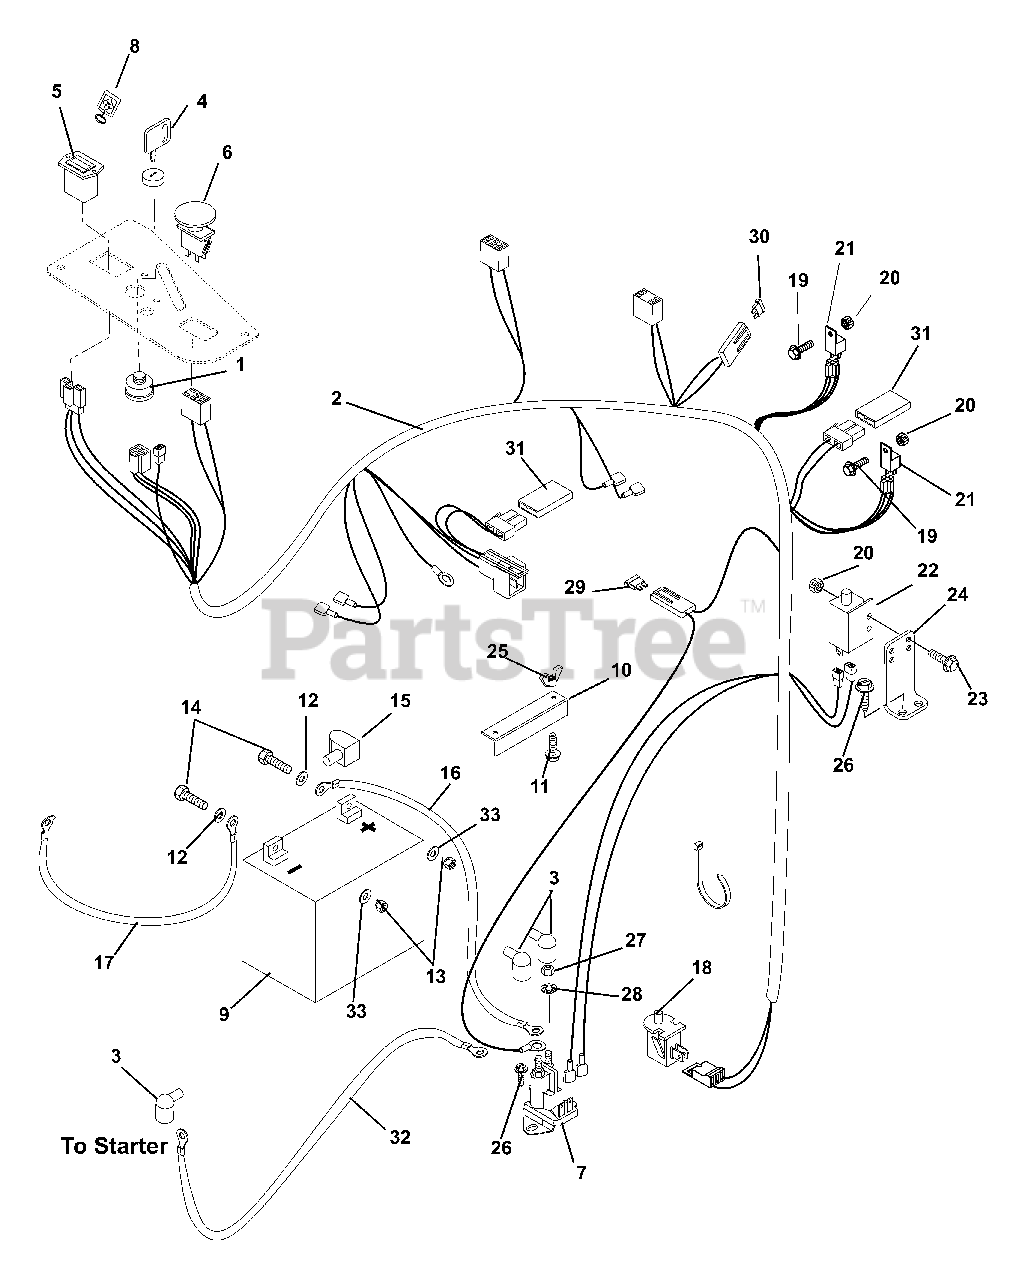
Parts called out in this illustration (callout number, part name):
1	Key Switch
2	Harness, Wiring IZ/CZ 6-Pin
3	Boot, Eyelet Terminal
4	Key with Shield
5	Hour Meter
6	Switch, Clutch With Retainer Ring
7	Solenoid
8	Key Chain
10	Hold Down
11	Bolt, Round Head Square Neck .25-20 x 7.50
12	Washer, Flat Steel .281 x .620 x .065
13	Nut, Hex .25-20
14	Bolt, Hex .25-20 x .75 Grade 5
15	Insulator
16	Cable, Positive Battery 9.00"
17	Ground Cable
18	Switch, Snap Mounting (N.O.)
19	Screw, Machine 10-24 x .50 Hex Washer Head
20	Nut, Locking Nylon 10-24 With Insert
21	Relay
22	Switch, Single Pole
23	Screw, Machine 10-24 x .75 Hex Washer Head
24	Mount, Brake Switch
25	Nut, Locking Wing .25-20
26	Screw, Tapping .25-20 x .50 Hex Washer Head
27	Nut, Jam .31-24
28	Washer, Locking .31 x .078 Regular
29	Fuse, 25 Amp
30	Fuse, 20 Amp
31	Diode, Connector Shell
32	Cable, Starter
33	Washer, Lock .25 x .062
